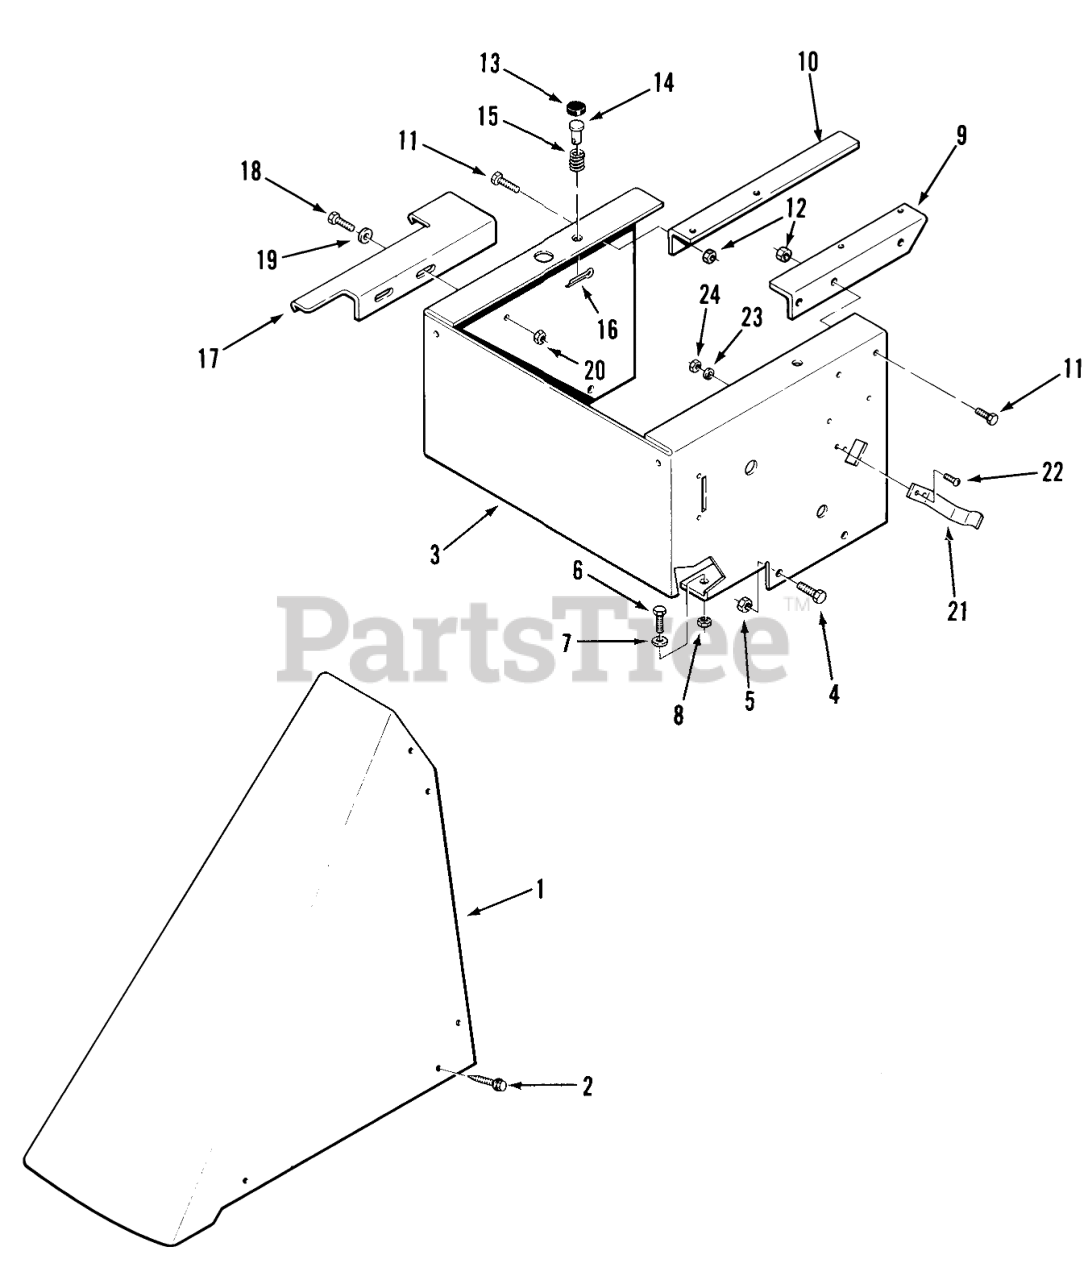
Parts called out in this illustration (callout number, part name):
1	COVER CONSOLE R
2	HEX WASHER STS
3	Seat Support
4	Bolt
5	NUT
6	Bolt
7	WASHER 5/16 SAE
8	Nut
9	ANGLE TANK SUPP. R
10	ANGLE TANK SUPP. R
11	Bolt
12	Nut
15	SPRING
16	Cotter Pin
17	PLATE SHIFT R
18	Bolt
19	WASHER 5/16 SAE
20	Nut
21	SPRING
22	Pan HD. Cross Rec. Machine Screw #4-40 x 3/8
23	#4 Lockwasher
24	Nut #4-40
